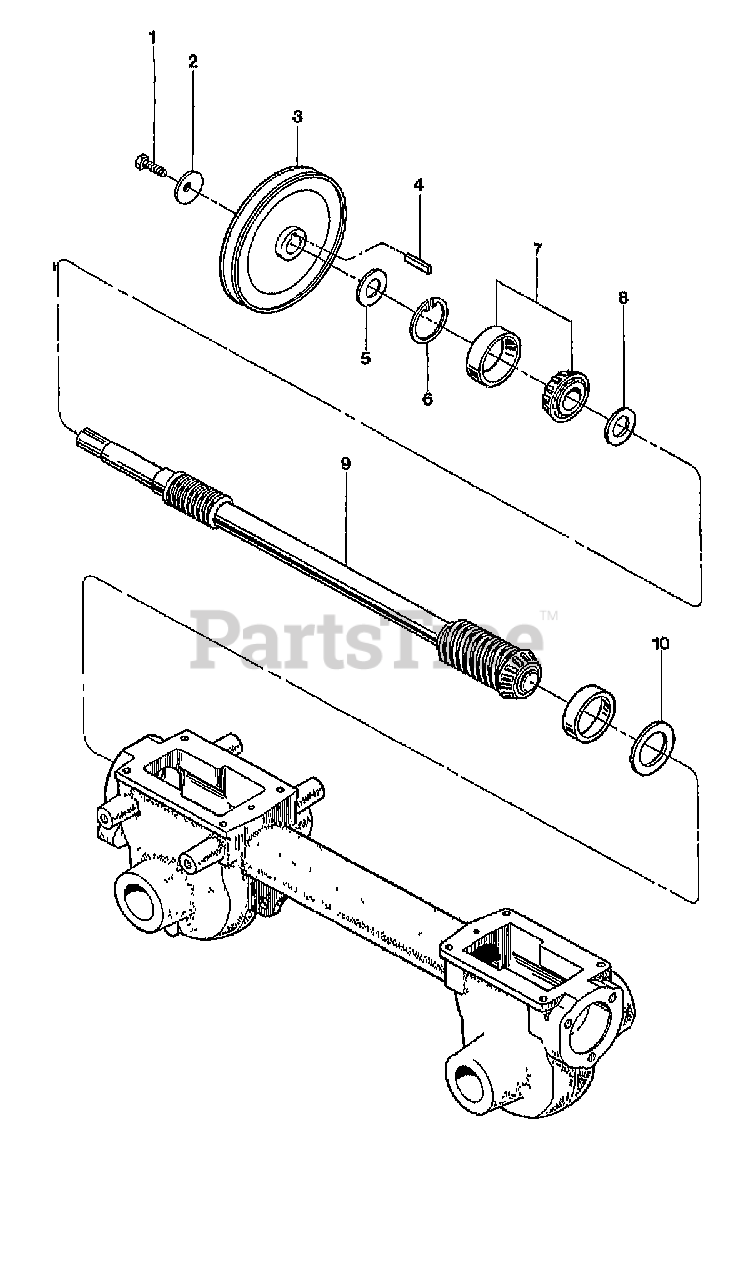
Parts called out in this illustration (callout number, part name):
1	SCR-HH 5/16-24X.75 G5 ZP
2	WASHER-.827X.331X.098
3	PULLEY-TRANSMISSION
4	KEY-.188 SQX1.0
5	WASHER-SHLDR HARDENED
6	RING-RETAINING 5000-181
7	KIT-BRG CONE&RACE-DRIVESHAFT
8	WASHER-#1.25X.75X.06
9	DRIVESHAFT-MACH
9	ASSM-DRIVESHAFT TUFFY {12155}
10	SHIM-1.75X1.5X.01 AS REQ'D
10	SHIM-1.75X1.5X.03 AS REQ'D
10	SHIM-1.75X1.5X.005 AS REQ'D
10	SHIM-1.75X1.5X.062 AS REQ'D
10	SHIM SET-DRIVESHAFT-HORSE
